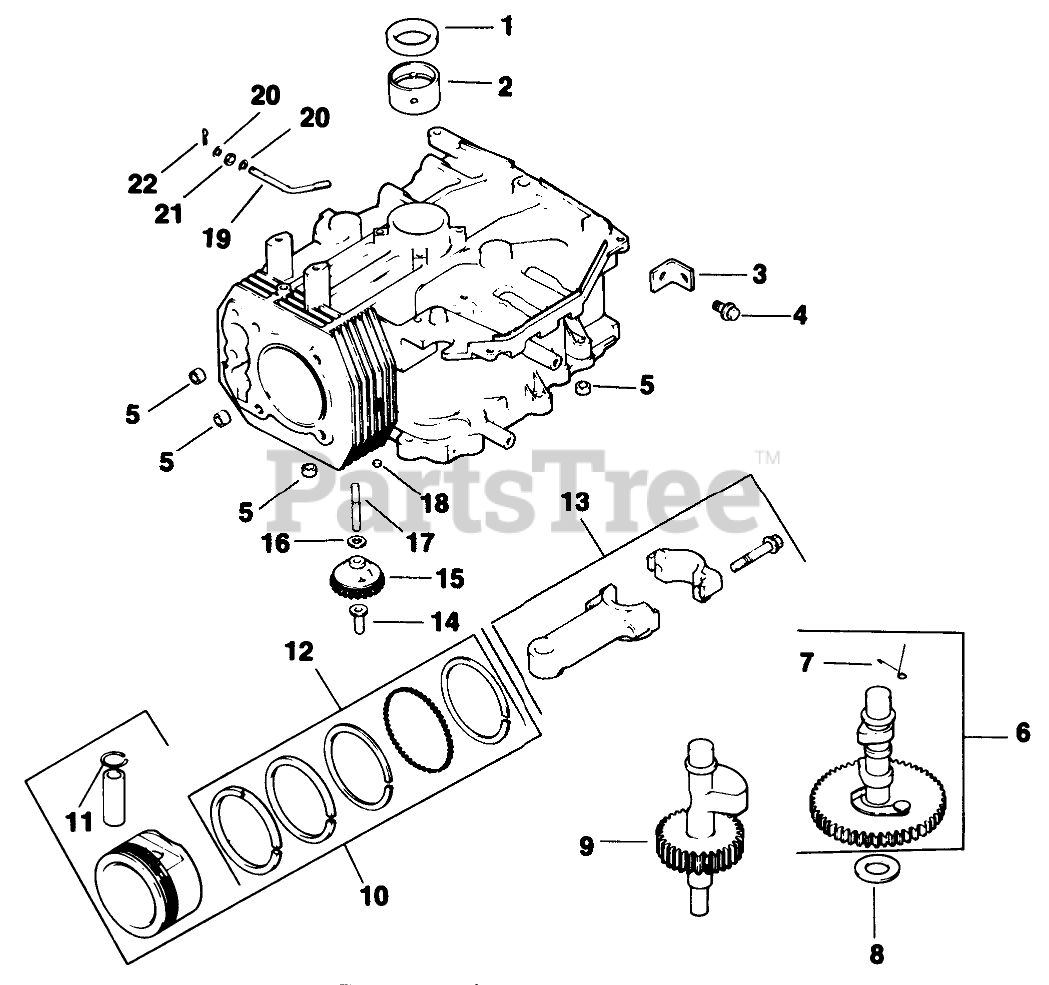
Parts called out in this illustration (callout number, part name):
1	Seal-Oil
2	Bearing-Crankshaft
3	Strap-Liting
5	Pin-Dowel
6	Camshaft Assembly
7	Spring-Actuating
8	Shim-Camshaft
9	Shaft-Balance
10	Piston W/Ring Set (Std.)
11	Retainer-Piston Pin
12	Ring Set (Std.)
13	Connecting Rod STD
14	Pin-Governor
15	Gear-Governor ASM
17	Shaft-Govenor Gear
19	Rod-Push
21	Seal
22	Pin-Hitch
